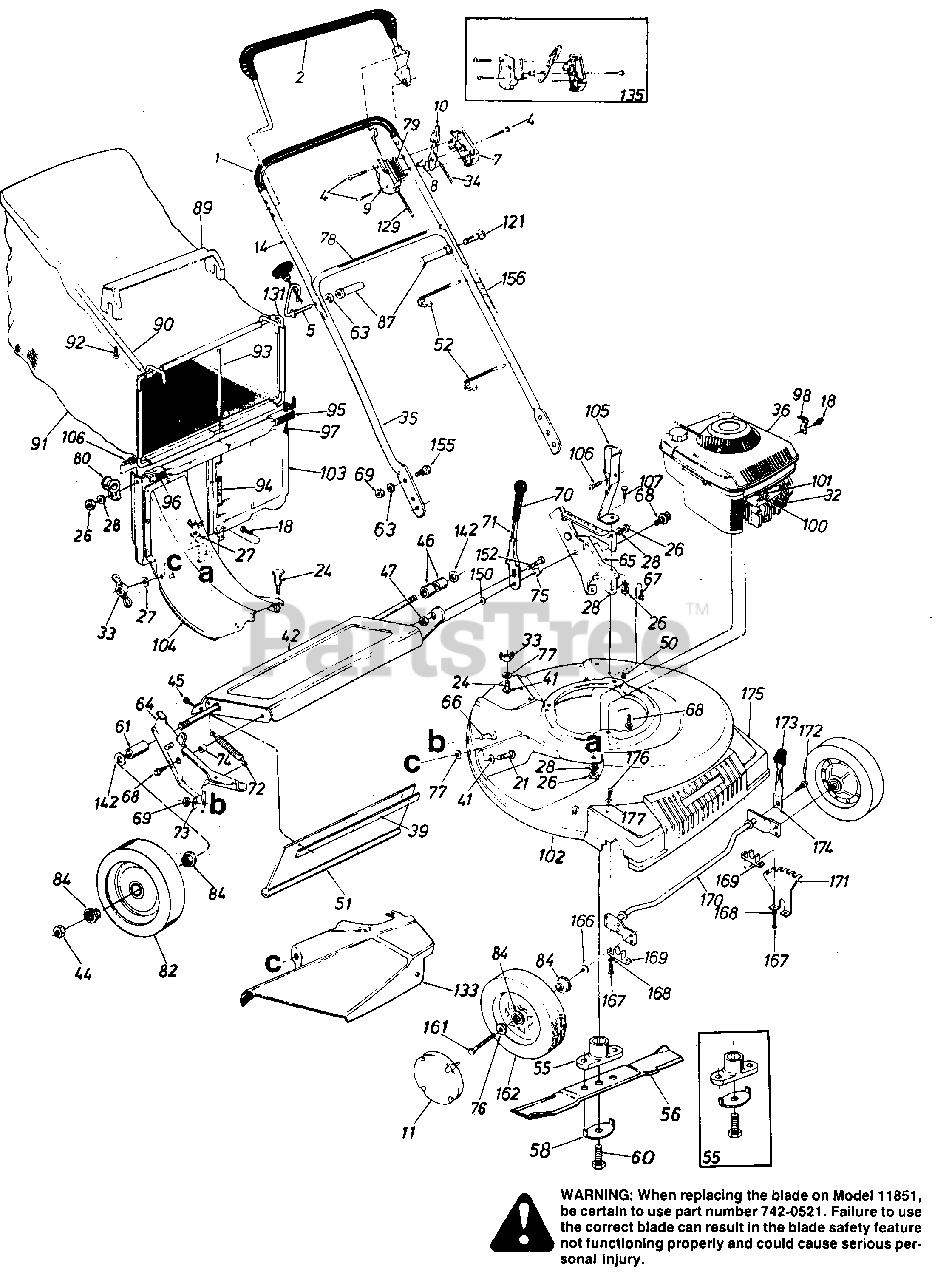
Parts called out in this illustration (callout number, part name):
2	Control Handle Ass'y. L.H.
4	Truss Mach. Scr. #12 x 1.5"
5	Rope Guide Bolt
7	Control Panel Half
8	Control Disc Pin
9	Clutch Panel Half
10	Throttle Control Lever
11	Hub Cap
14	Upper Handle Chrome
18	Hex B-Tap Scr. #10 x .38"
21	Carriage Bolt 1/4-20 X .62"
24	Shoulder Bolt .312 Dia. x .18 Lg. Special
26	Hex Nut 1/4-20 Thd.
27	Bell-Wash. 1/4" I.D.
28	L-Wash. 1/4" I.D.
32	Spark Plug Insulator
33	Wing Nut
34	Throttle Control Wire 58"
35	Lower Handle Chrome
36	Engine
39	Retaining Strip
41	Fl-Wash. .344" I.D. x .62"
42	Rear Axle Ass'y.
44	Hex L-Nut 1/2-20 Thd.
45	Hex AB-Tap Scr. 1/4 X .62"
46	Spacer.526" I.D.
47	Hex Patch L-Nut 3/8-24 Thd.
51	Rear Flap
52	Cable Tie
55	Blade Adapter Kit
56	21" Blade
58	Blade Bell-Wash.
60	Hex Bolt 7/16-20 x 1.5" Grade 5*
61	Sleeve .526" I.D.
63	L-Wash .5/16" I.D.
64	R.H. Handle Wheel Brkt. Ass'y.
65	L.H. Handle Wheel Brkt. Ass'y.
66	Carriage Bolt 5/16-18 x .62"
67	Hex Wash. Hd. B-Tap Scr. 5/16-18
68	Hex Wash. Hd. TT-Tap Scr. 3/8-16
69	Hex Nut 5/16-18 Thd.
71	Height Adj. Lever
72	Extension Spring 3.80" Lg.
73	Bell-Wash. 5/16" I.D.
74	Spacer.385" I.D.
75	Shld. Spacer .5" Dia.
76	Fl-Wash. .531" I.D.
77	Bolt Retainer 1/4 X .50" O.D.
78	Instruction Label
79	Control Label
80	Rope Guide
82	Wheel Ass'y. Comp.
84	Flange Ball Bearing 1/2" I.D.
87	Catcher Support Pin
89	Bag Handle
92	Hex AB-Tap Scr. #12 x 1.25" Lg.
93	Chute Rod .188" Dia.
94	Torsion Spring
95	Door Clip
96	Panel Clip
97	Hex AB-Tap Scr. 1/4" X .75"
98	Casing Clamp
100	Hex B-Tap Scr. #10 x .62"
101	Casing Clamp
104	Top Discharge Chute Ass'y.
105	Grass Catcher Bracket
106	Truss Mach. Scr. 1/4-20 x .50" Lg.
107	Hex Bolt 1/4-20 X .50" Lg.
121	Curved Carr. Bolt 5/16-18 x 1.75" Lg.
129	Control Cable 46"
131	Front Catcher Frame
133	Side Chute Deflector Ass'y.
135	Kit Control Housing Comp.
142	Fl-Wash. .510" I.D. x .75"
150	Fl-Wash. 3/8" I.D. x 1.0"
152	Hex Bolt 3/8-24 x .75" Lg.
155	Truss Mach. Scr. 5/16-18 x .75"
156	Plastic Tubing
161	Front Axle Bolt
162	Wheel Ass'y. Comp.
166	Bell-Wash. .400" I.D. x .88
167	Hex Wash. Hd. B-Tap Scr. 1/4-20
168	L-Wash. 1/4" I.D.
169	Block Bushing
170	Axle Ass'y.
171	Height Adj. Bracket
172	Hex Wash. Hd. B-Tap Scr. 1/4-20 X .75" Lg.
173	Knob
174	Spring Lever
175	Plastic Front End
176	Truss B-Tap Scr. 5/16 x .75"
177	Bell-Wash. 5/16" I.D. x 5/8
